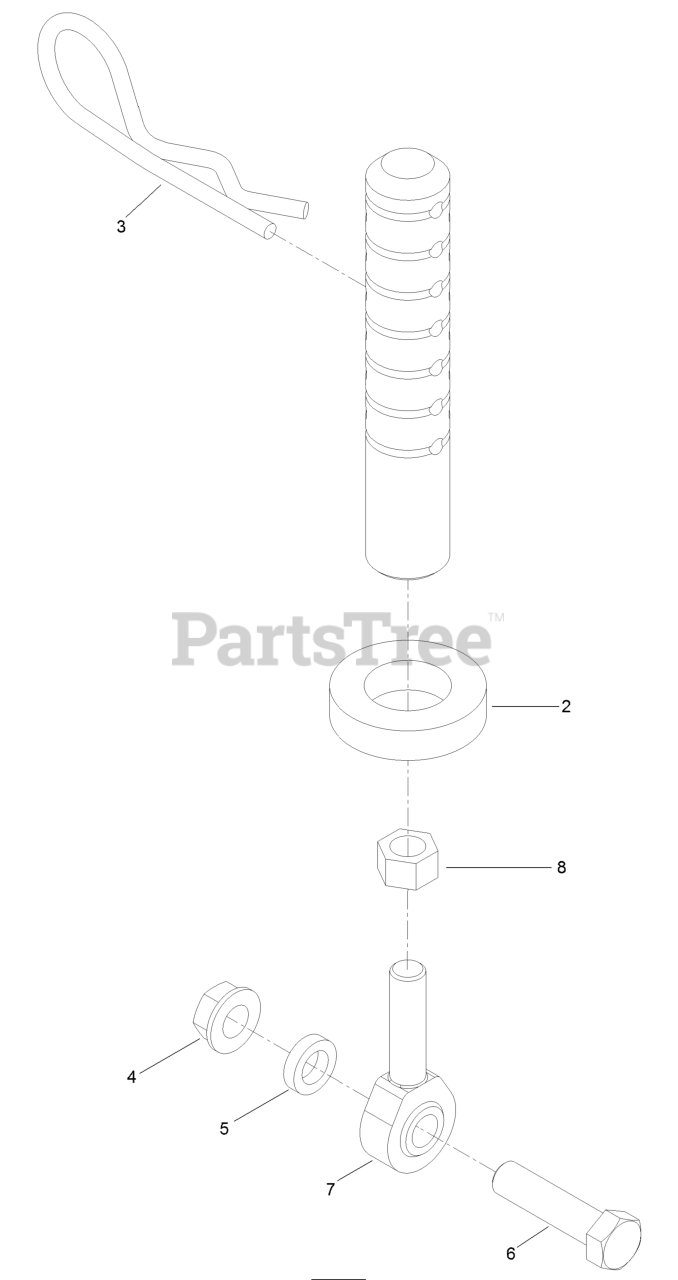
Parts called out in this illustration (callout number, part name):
2	SPACER-DECK SUPPORT
3	PIN-CUT HEIGHT
4	NUT-HHF, WHIZ
5	SPACER-IDLER
6	SCREW-HH
7	BALLJOINT
8	NUT-HJ
